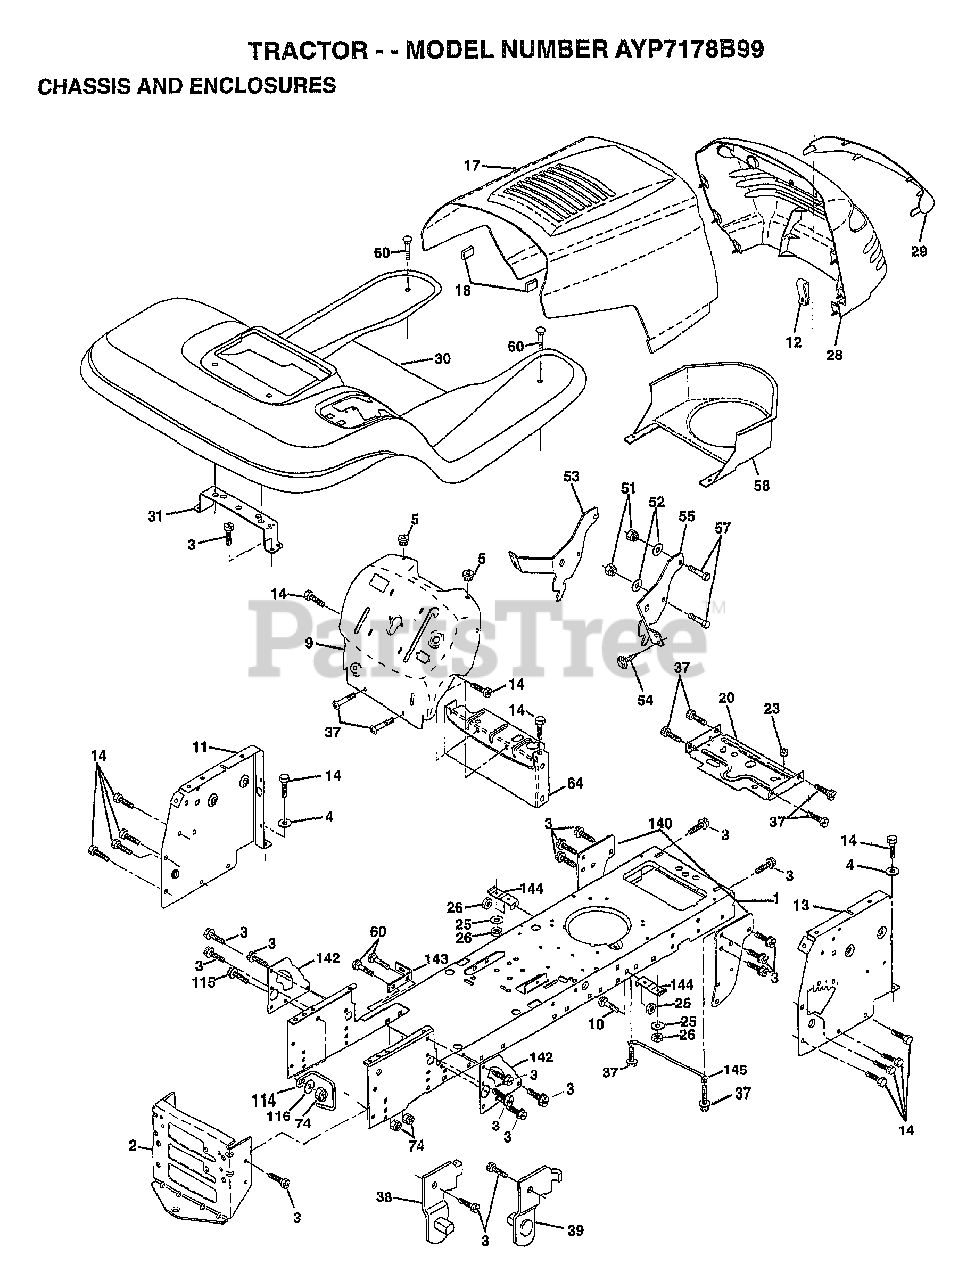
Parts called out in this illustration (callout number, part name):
1	CHASSIS.STLT
3	SCREW
4	WASHER
5	BUMPER-HOOD/DASH
11	"PANEL-DASH,LH"
12	CLIP.TINNERMAN
13	"PANEL-DASH,RH"
14	SCREW LT
17	HOOD.STEEL.ASSY
20	"PLATE-MTG,BATT/FU"
25	WASHER
26	NUT
28	GRILL
29	GRILLE.LENS
30	FEND/FTREST PNT
31	BRACKET SUPT FEND
37	SCREW LT
38	BRACKET ASM LH
39	BRACKET ASM RH
51	NUT
52	WASHER
53	BRACKET.GRILLE.LH
54	SCREW.HEX.WS.HD
55	BRACKET.GRILLE.RH
58	AIR DUCT
60	BOLT
64	DASH-LOWER
114	"KEEPER-BELT,RR.LH"
115	SCREW
116	WASHER
140	BRKT SUSPENSION
142	PLATE.REINFORCEMENT
143	"BRKT-S'BAR,CHASSI"
144	BRKT-FOOTREST
145	"ROD POVOT,CHASSIS"
